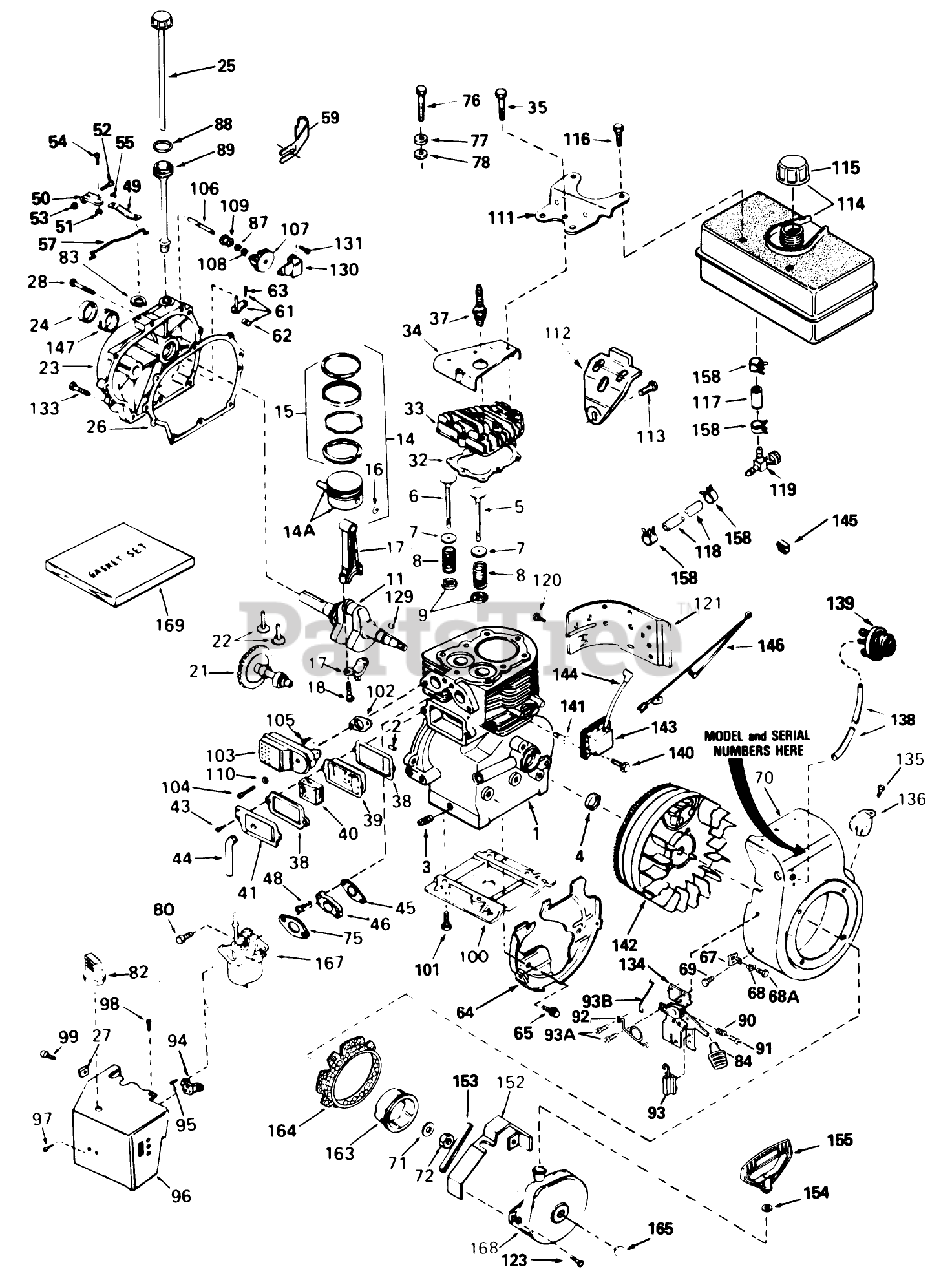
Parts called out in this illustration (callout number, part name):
1	Cylinder Assy. (Incl. Ref. #2, 3 4)
2	Pin-Dowel
3	Plug-Drain, Oil (SQH 1/4-18)
4	Oil Seal
5	Valve, Intake (Standard)(Incl. No. 9)
6	Valve, Exhaust (Standard)(Incl. No. 9)
7	Cap-Spring, Valve
8	Spring-Valve
9	Keeper-Spring, Valve
11	Crankshaft
14	Piston, Pin Ring Assy. (Std.)(Incl. Ref. #14A, 15 16)
14A	Piston Pin Assy. (Std.)(Incl. Ref. #16)
15	Ring Set (Std.)
17	Rod Assy., Connecting (Incl. Ref. #18)
18	Bolt-Connecting Rod
21	Camshaft
22	Lifter-Valve
23	Cover, Cylinder (Incl. Nos. 24 106)
24	Oil Seal
25	Dipstick
26	Gasket-Cover, Cylinder
27	Nut-U Type
28	Screw (1/4-20 x 1-1/4)
32	Gasket-Head, Cylinder
33	CYLINDER HEAD
34	Cover-Head, Cylinder
35	Screw (5/16-18 X 2-1/2)
37	Spark Plug-Resistor (R J19 L M)
38	Gasket-Breather
39	Body-Breather
40	Element-Breather
41	Cover-Valve
43	Screw
44	Tube-Breather
45	Gasket-Intake
46	481-1279 SENATOR RO
48	Screw
49	Lever-Governor
50	Clamp-Lever, Governor
51	Nut-Lock
52	Screw
53	Nut-Lock
54	Screw
55	Washer-Lock
57	Governor Link
59	Clip-Tube, Fill
61	Rod, Governor (Incl. Nos.62 63)
62	Yoke-Governor
63	Screw (6-40x5/16)
64	Baffle-Blower Housing
65	Screw (1/4-20x19/32)
67	Bracket
68	Grommet
68A	Screw (8-32 x 3/8)
69	Screw
70	Housing, Blower (Incl. Ref. #135 136)
71	Washer-Belleville
72	Flywheel Nut
75	Gasket-Carburetor
76	Screw (5/16-18 X 2-1/2)
77	Washer-Belleville
78	Washer-Flat
80	Screw (T-30, 1/4-20 X 27-32)
82	Knob-Choke
83	Ring-Retaining
84	Knob-Control
87	Washer-Flat
88	O-Ring
89	Tube-Fill, Oil
90	Spring-Compression
91	Screw
92	Spring-Throttle
93	Terminal
93A	Screw (10-32 x 1/2)
93B	Link-Throttle
94	Bracket-Choke
95	Screw (10-32 x 1/2)
96	Carburetor Cover
97	Screw (8-32 X 5/16)
98	Screw (10-32x1/2)
99	Screw (8-32 x 3/8)
100	Base Engine
101	Screw
102	Gasket Exhaust
103	Muffler
104	Screw (5/16-18 X 2)
105	Screw
106	Shaft-Governor
107	Governor Gear ASM
108	Ring-Retaining
109	Spool-Governor
110	Washer
111	Bracket-Fuel Tank
112	Bracket-Fuel Tank
113	Screw (1/4-20x19/32)
114	Fuel Tank (Incl. Ref. #292 301)
115	Cap-Fuel
116	Screw (1/4-15x7/8)
117	Line-Fuel
118	Line-Fuel (8.62)
119	Valve-Shut Off
120	Screw
121	Extension-Blower Hsng.
123	Screw
129	Key-Flywheel
130	Bracket, Governor
131	Screw (10-24x1/2)
133	Screw
134	Bracket-Control (Includes 19, 203, 204, 206)
135	Screw (8-32 x 3/8)
136	Screw
138	Line-Primer
139	Primer-Asm
140	Screw
142	Flywheel
143	Solid State
144	Cover-Spark Plug
145	Clip-Wire
146	Ground Wire
147	Bushing-Crankshaft
152	Guard-Starter
153	Seal, Snowguard
154	Washer
155	Handle-Starter, Mitten Grip
158	Clamp-Line, Fuel
163	Cup-Starter
164	Screen-Starter
165	Plug Starter
167	Carburetor (Incl. Ref. #75)
168	Starter-Rewind
169	Gasket Set (Incl. Items Marked *)
